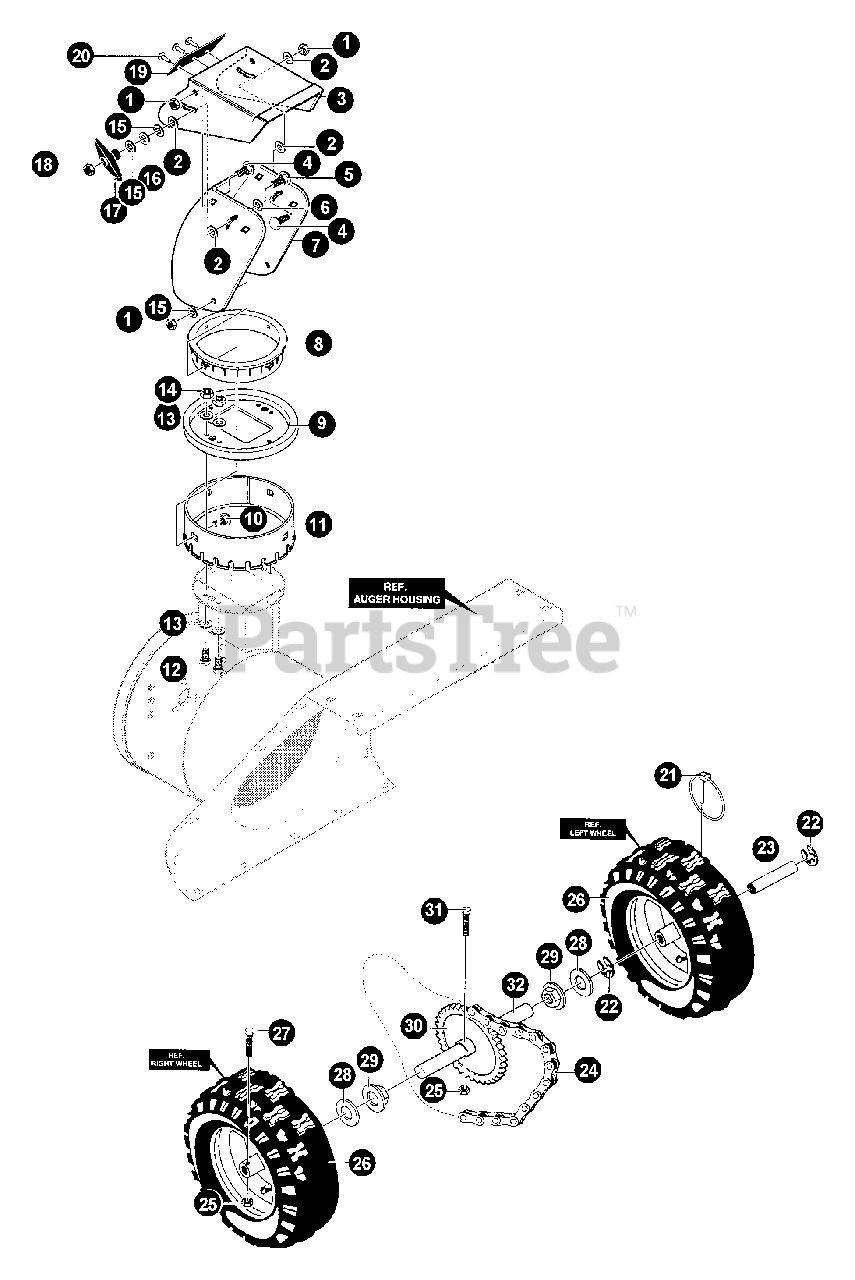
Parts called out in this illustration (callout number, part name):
1	NUT - 5/16-18
2	WASHER - PLASTIC
3	CHUTE - UPPER
4	SCREW - 5/16-18 X 3/4"
5	BOLT - 5/16-18 X 1"
6	WASHER - PLASTIC
7	CHUTE - LOWER
8	RETAINER, RING INNER
9	COLLAR
10	BOLT, 5/16-18X1.00 CARRLN
11	RETAINER, RING OUTER
12	SCREW - 1/4-20
13	WASHER
14	NUT - 1/4-20
15	WASHER
16	LOCKWASHER
17	KNOB, T 2 BLADE W/5/16-18 NUT
18	NUT - 5/16-18
19	SKIRT, CHUTE EXTENSION
20	RIVET - POP
21	PIN, KLIK
22	RING, RETAINING
23	BUSHING, WHEEL 4" LG
24	CHAIN, ROLLER 420X41
25	NUT - 1/4-20
26	WHEEL ASSY
27	SCREW - 1/4-20 X 1.75"
28	WASHER
29	BEARING, FLANGE
30	SPROCKET, HUB
31	SCREW - 1/4-20 X 2.25"
32	SHAFT, AXLE 6.15
